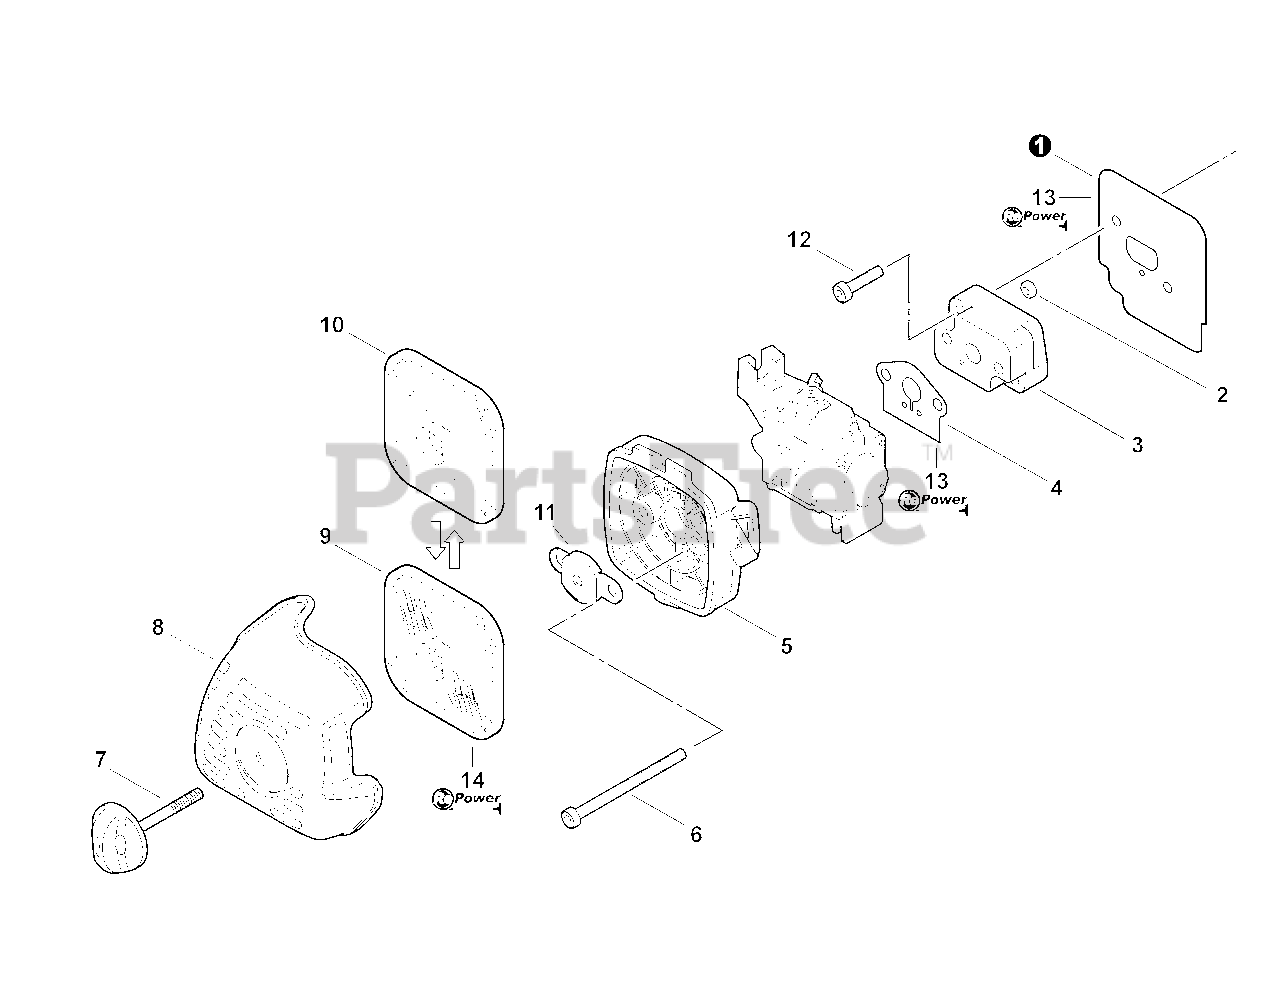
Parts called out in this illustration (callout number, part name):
1	SHIELD, INTAKE
3	INSULATOR, INTAKE
4	GASKET, INTAKE
5	CASE, AIR FILTER
6	SCREW - 5×65 -- TORX
7	THUMBSCREW
8	COVER, AIR FILTER
9	FILTER, AIR - DOUBLE LAYER
10	FILTER, AIR - SINGLE LAYER
11	PLATE, PREVENT
12	SCREW - 5×20
13	GASKET KIT
14	RePower TUNE-UP KIT
